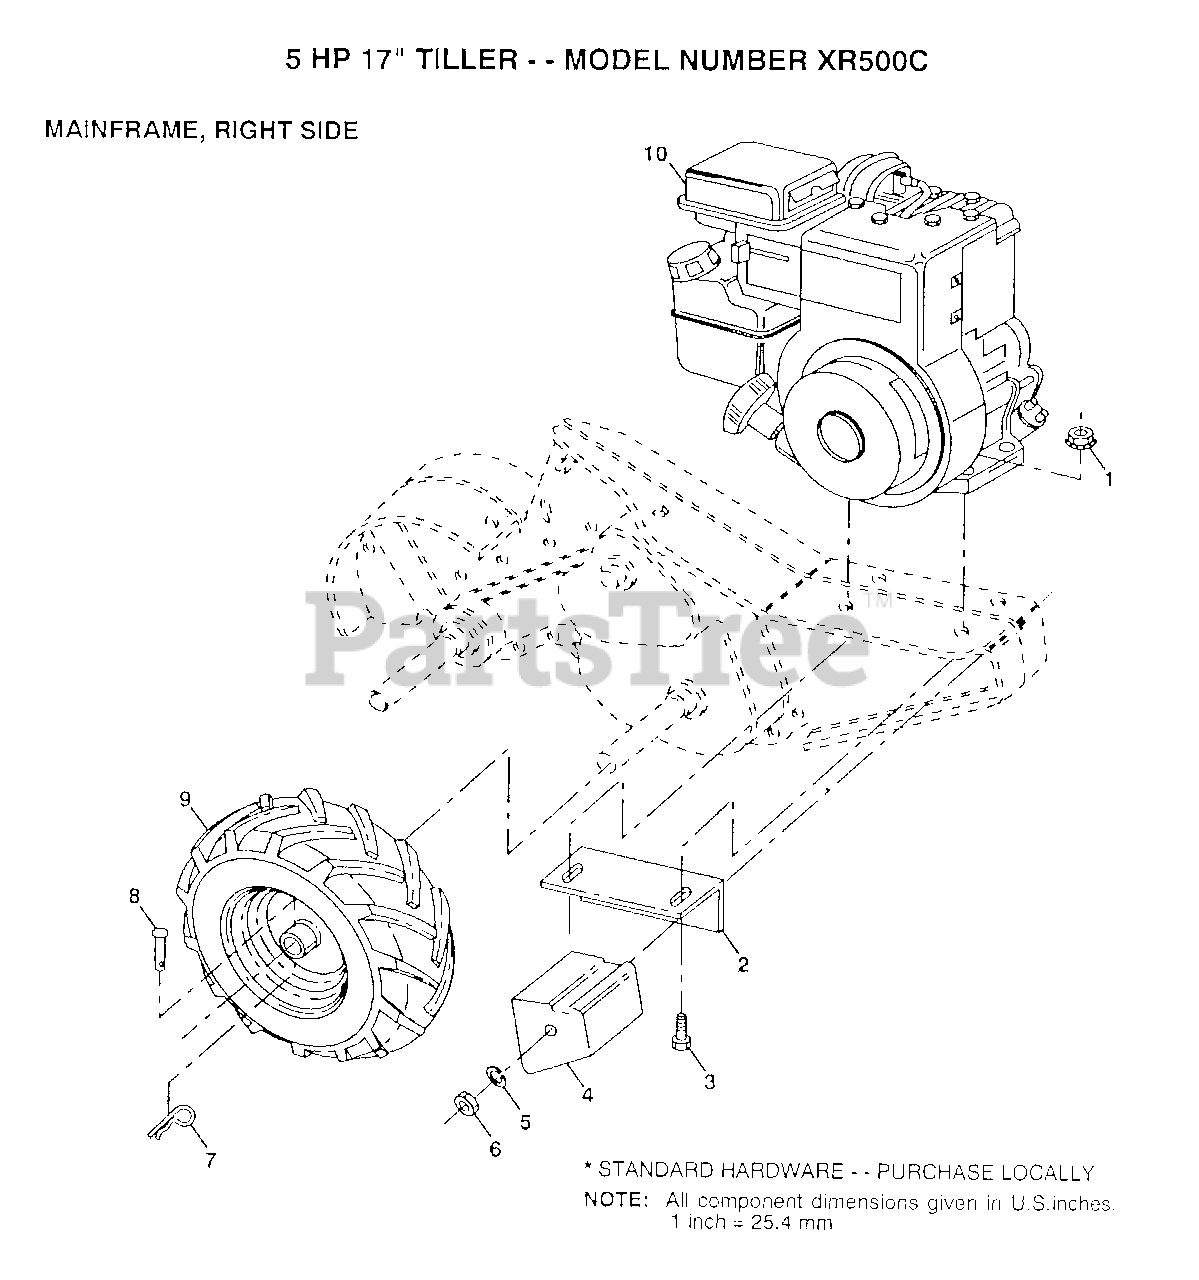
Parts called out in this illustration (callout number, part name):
2	BRACKET RH CRT
3	BOLT.HEX.5/16-1.5
4	COUNTERWEIGHT CRT
5	LOCKWASHER
6	NUT.HEX.3/8-16UNC
7	RETAINER M
8	RIVET.DRILL.1.75
9	TIRE.CHV.13X5.0-6
9A	RIM
